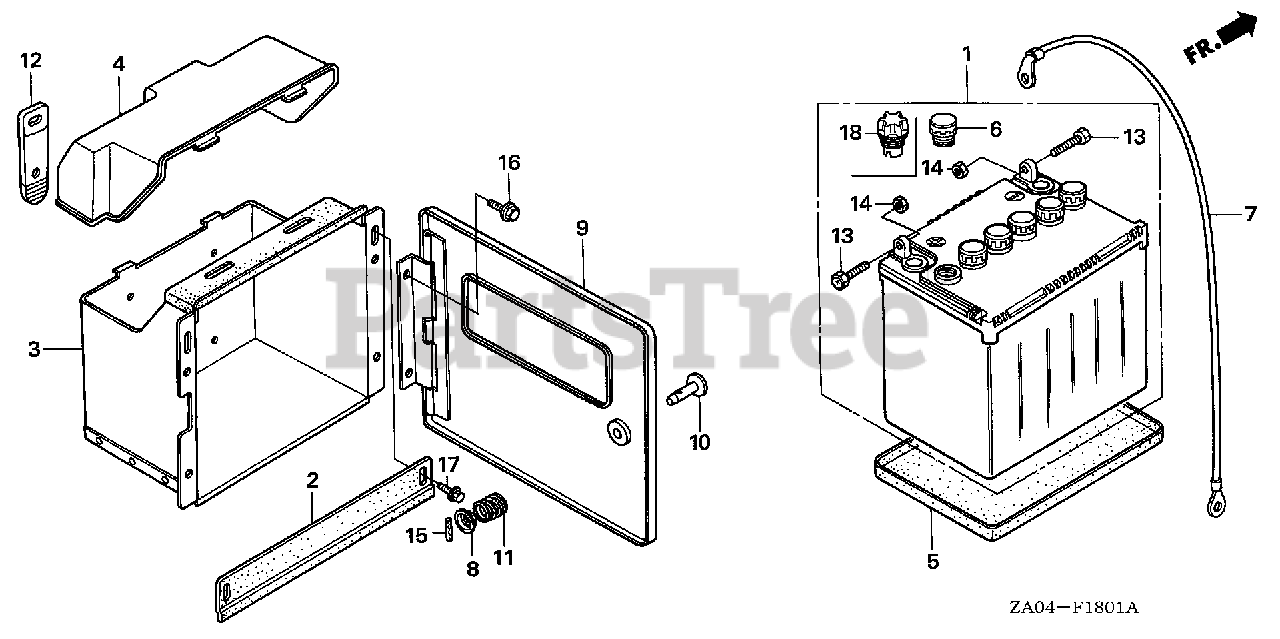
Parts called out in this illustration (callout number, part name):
1	BATTERY ASSY. (34A19L-MF) (YUASA)
2	PLATE, BATTERY SETTING
3	BOX, BATTERY
4	COVER, BATTERY BOX
5	TRAY, BATTERY
6	PLUG, VENT (YUASA)
7	CABLE, BATTERY GROUND
8	RETAINER, LOCK SPRING
9	COVER, BATTERY *B9* (ATLANTIS BLUE)
10	PIN, COVER LOCK
11	SPRING, COVER LOCK
12	BAND, TOOL BOX
13	BOLT, BATTERY TERMINAL
14	NUT, BATTERY TERMINAL
15	PIN, SPRING (3X18)
16	BOLT, FLANGE (6X10)
17	BOLT, FLANGE (6X12)
